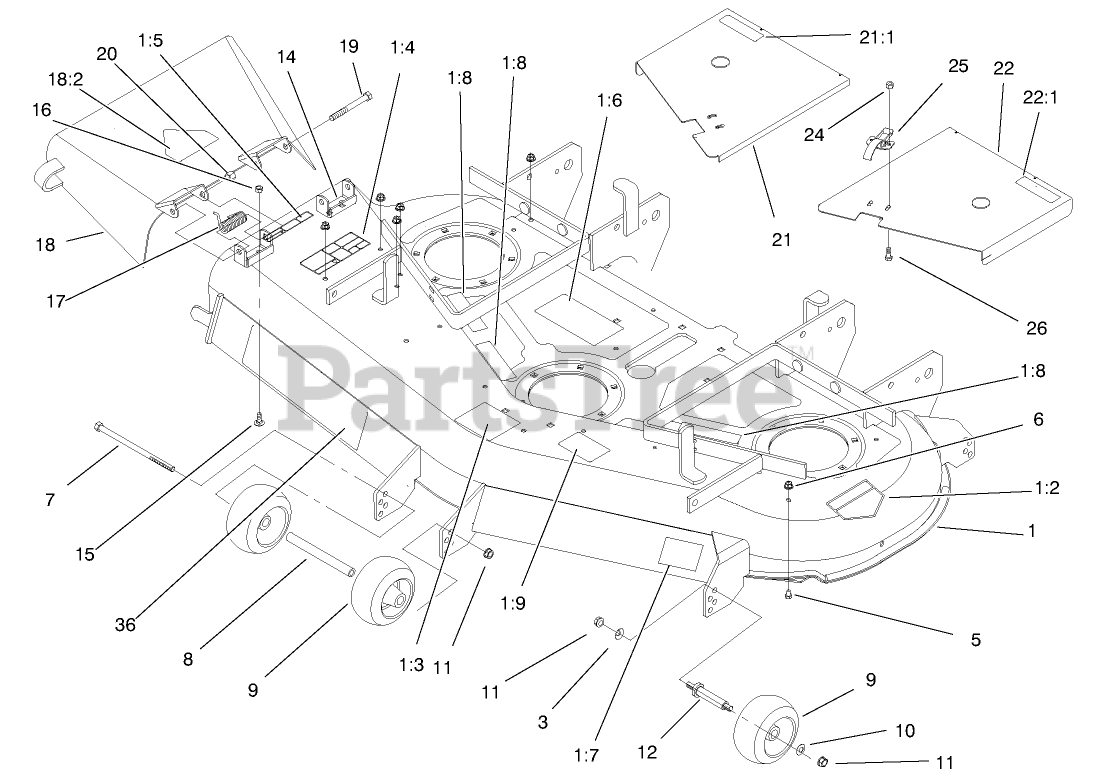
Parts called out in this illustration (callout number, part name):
1	Deck ASM
1:2	DECAL-DANGER
1:3	DECAL-WHEEL, GAGE
1:4	DECAL-DANGER, THROWN OBJECT
1:5	DECAL-DANGER
1:6	DECAL-BELT ROUTING
1:7	DECAL
1:8	DECAL-COVER, MISSING
1:9	DECAL-TORQUE, BLADE BOLT
3	WASHER-BELLEVILLE
5	SCREW-HH
6	NUT-HF
7	SCREW-HH
8	SPACER-WHEEL
9	WHEEL-GAGE
10	Washer
11	NUT-HHF, WHIZ
12	SPACER
14	BRACKET-PIVOT
15	SCREW-CARR
16	NUT-LOCK, CONE
17	SPRING
18	DEFLECTOR ASM, 52" W/DECAL
18:2	DECAL-DANGER
19	SCREW-HH
20	NUT-HEX
21	COVER ASM-RH
21:1	DECAL-DANGER
22	LH COVER ASM
22:1	DECAL-DANGER
24	NUT-LOCK, FLANGE
25	CLAMP-SLOTTED
26	SCREW-HWH
36	DECAL
